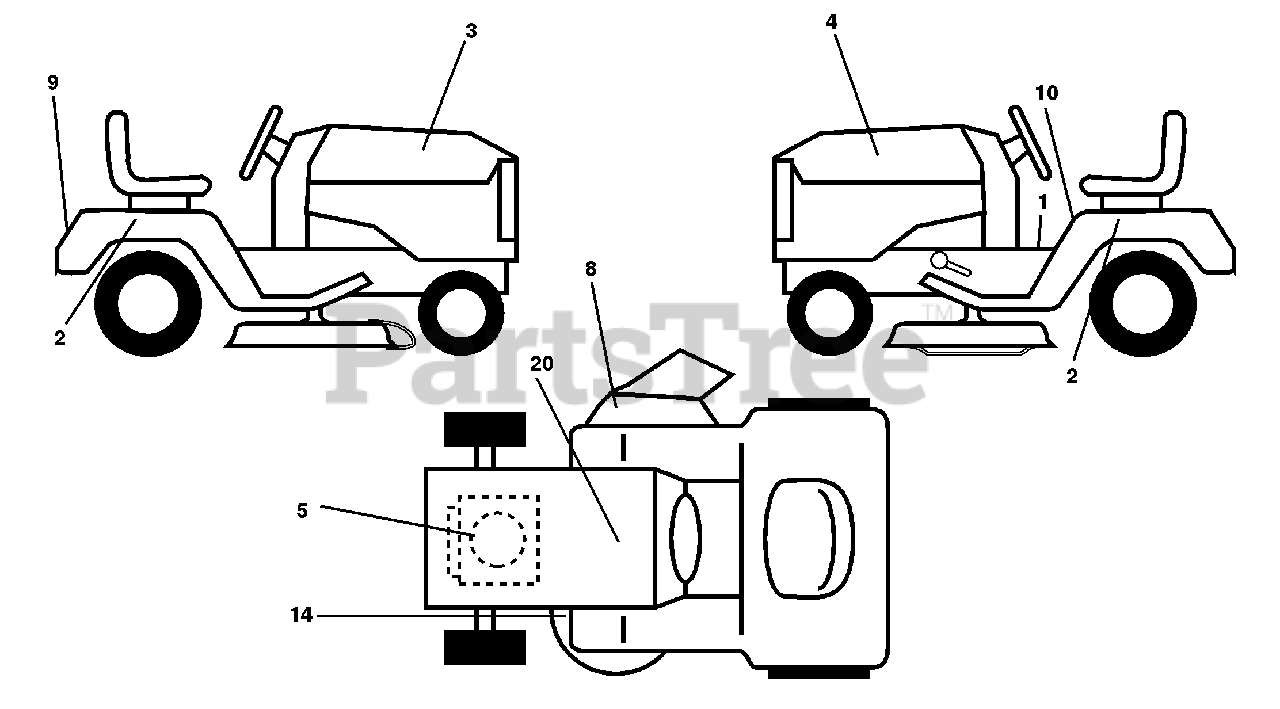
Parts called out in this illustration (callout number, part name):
1	Decal Oper Step Thru E/F
2	Decal Fender Auto Husq. Radius
3	Decal Hood RH
4	Decal Hood LH
5	Decal Engine
8	Decal Warning
9	Decal Fender Husq
10	Decal Fender Danger E/F
14	Decal V-Belt Schematic
20	Decal Bat Dan/Psn
